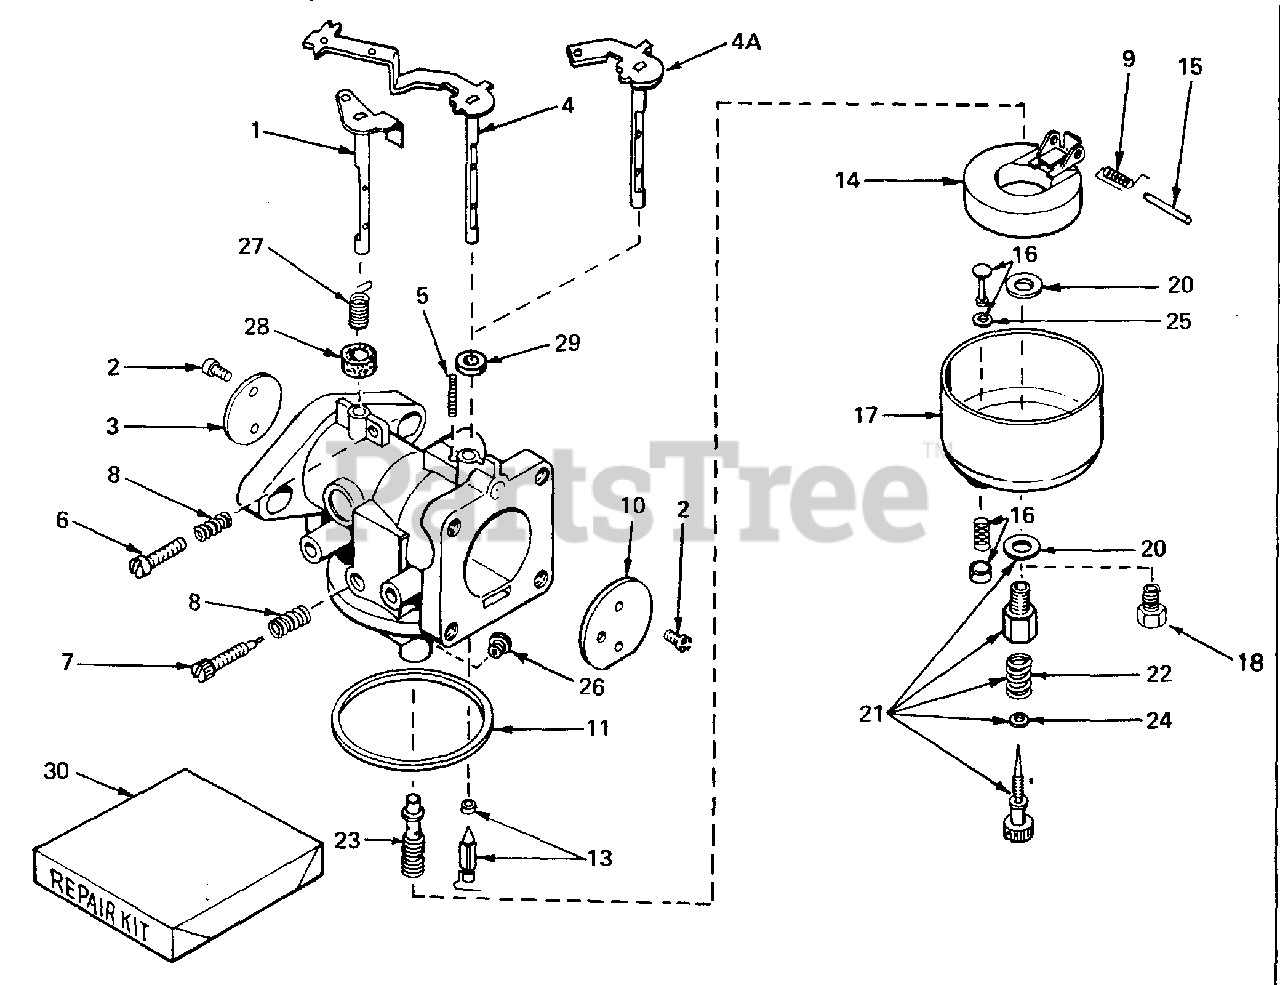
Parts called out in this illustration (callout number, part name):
1	Throttle Shaft & Lever Assembly Incl. 2
3	Throttle Shutter
4	Choke Shaft & Lever Assembly (Incl.2)
5	Choke Stop Spring
6	Throttle Adjusting Screw
7	* Idle Adjusting Needle
8	Adjusting Spring
9	Float Shaft Spring
10	Choke Shutter
11	* Bowl-to-Body Gasket
13	* Valve, Seat, & Spring Assembly Incl. 9
15	* Float Shaft
17	Fuel Bowl
18	Float Bowl Nut
20	* Bowl-to-Body Gasket
23	Main Nozzle
26	Main Fuel Jet
28	Throttle Shaft Dust Seal
29	Choke Shaft Dust Seal
30	Repair Kit (Incl. items marked PK in notes. Incl. (1) each of part #'s271 06, 27109, 27110, 27112, 631687
